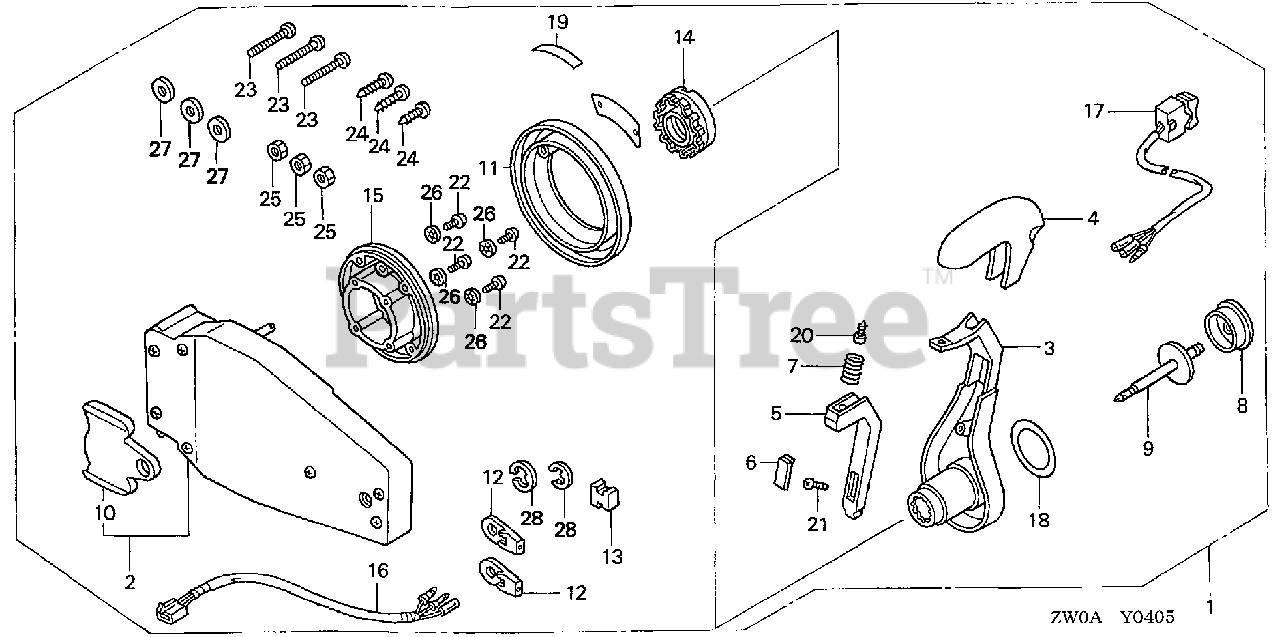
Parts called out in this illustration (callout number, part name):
1	BOX KIT, REMOTE CONTROL
2	HOUSING ASSY., L. (INNER)
3	HANDLE, REMOTE CONTROL
4	COVER, GRIP
5	ARM, NEUTRAL LOCK
6	COVER, LOCK ARM
7	SPRING, NEUTRAL LOCK ARM
8	BUTTON, THROTTLE
9	SHAFT, THROTTLE BUTTON
10	PLATE, DWELL
11	COVER ASSY.
12	TERMINAL, CABLE
13	SPACER, CABLE CLAMP
14	HOLDER, NEUTRAL LOCK
16	SUB-HARNESS ASSY., POWER
17	SWITCH ASSY., POWER TRIM-TILT
18	MARK, HANDLE FLUSH MOUNT
19	MARK, FLUSH MOUNT
20	SCREW, PAN (5X16)
21	SCREW, TRUSS (4X12)
22	SCREW, PAN (5X30)
23	SCREW, PAN (6X35)
24	SCREW, TAPPING (6X30)
25	NUT, HEX. (6MM)
26	WASHER, LOCK (5MM)
27	WASHER, PLAIN (6MM)
28	E-RING (6MM)
